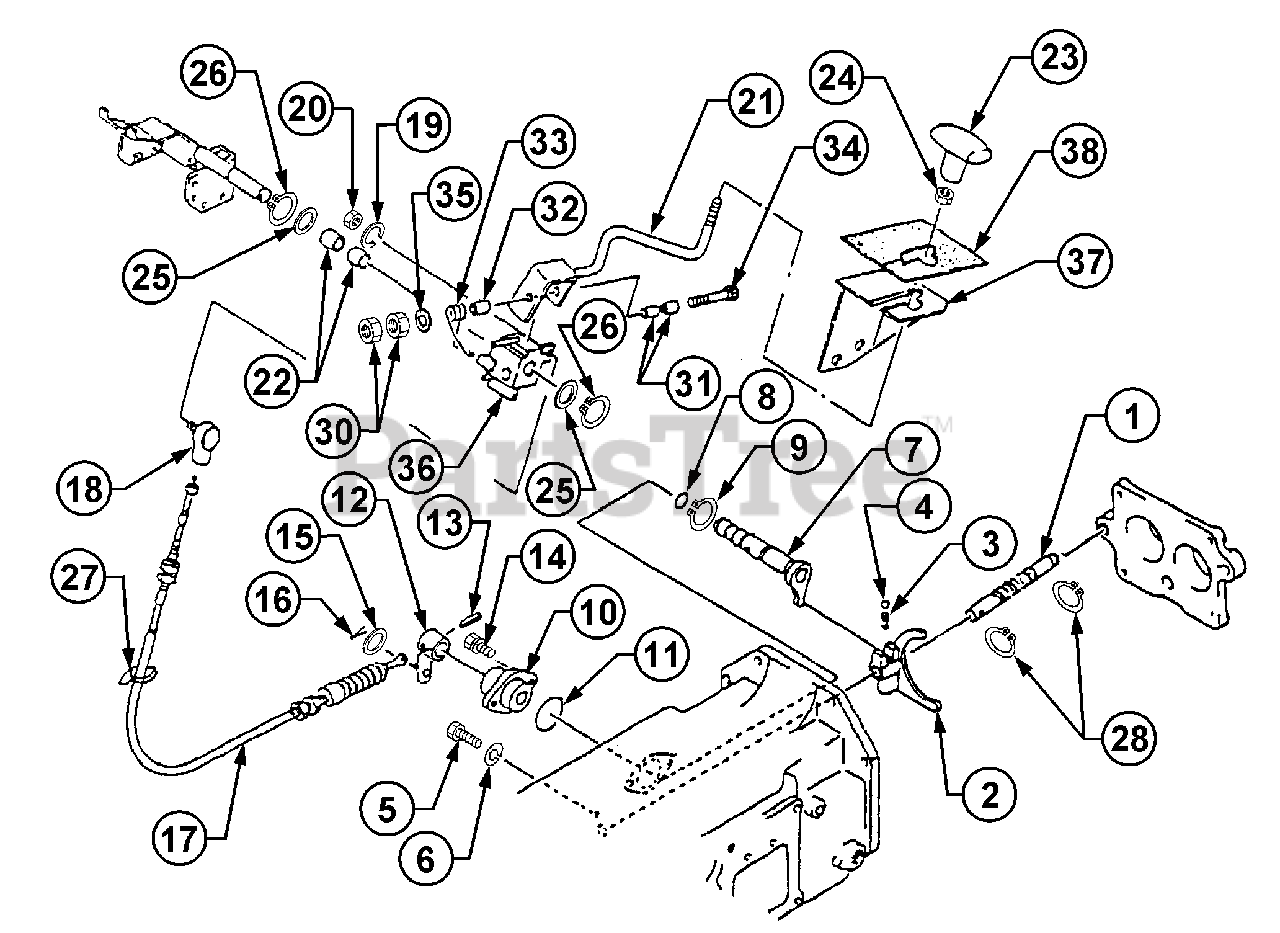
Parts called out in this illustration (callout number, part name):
1	Rail, Shuttle
2	Fork, Shuttle
6	Washer, Spring
12	Link, Shuttle
14	Bolt, w/Washer
17	Wire, Control
19	Washer, Spring
21	Lever, Shuttle
